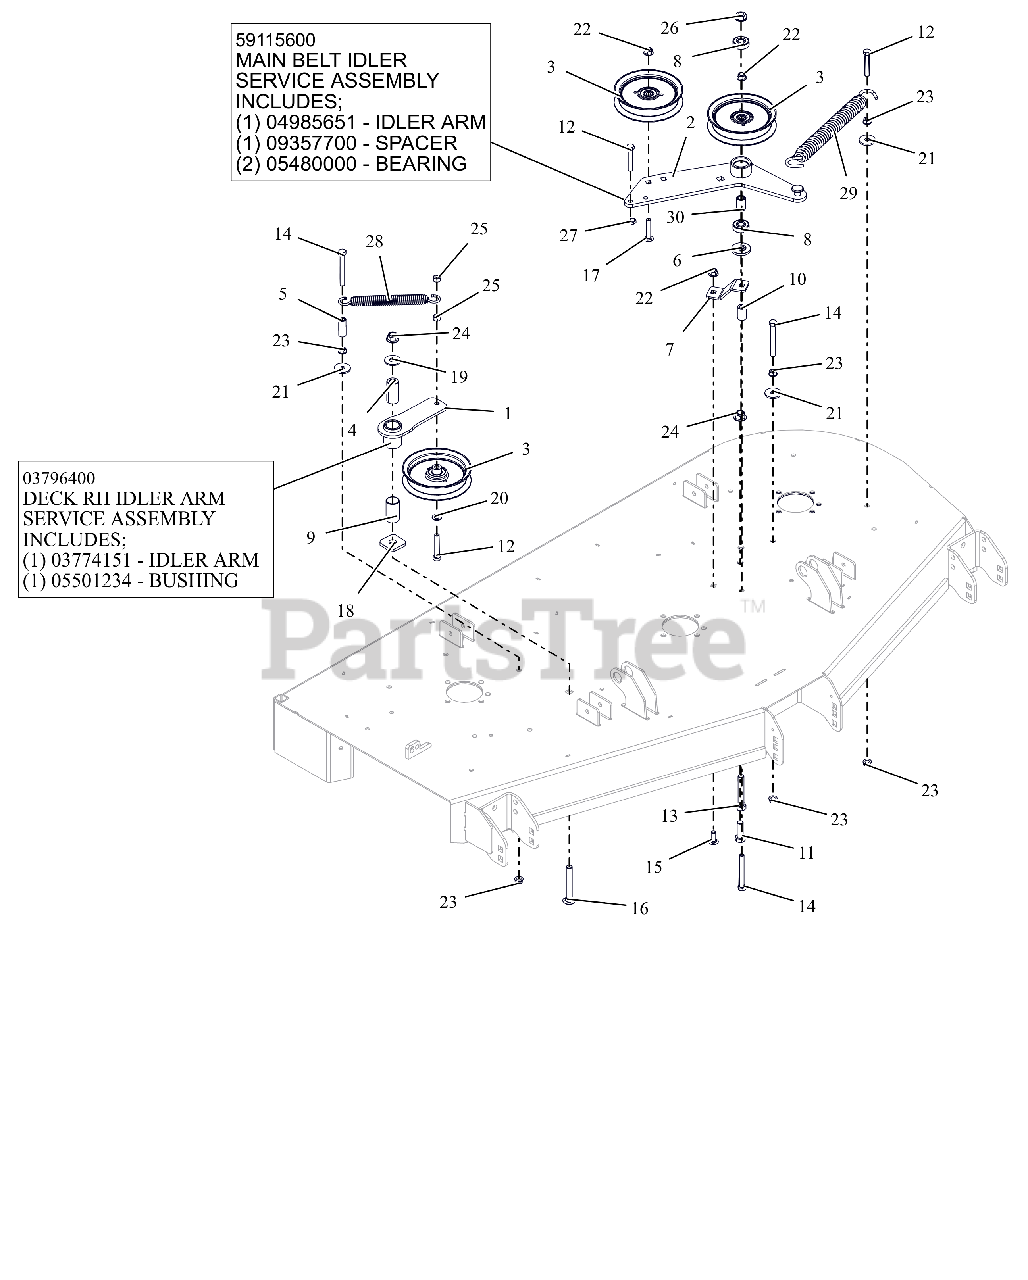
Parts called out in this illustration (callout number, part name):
1	WMT, IDLER ARM - BLACK
1	ASM, IDLER ARM (DECK)
2	DECK PTO IDLER ARM WLDMT - BLK
2	ASSEMBLY, MAIN BELT IDLER
3	IDLER, FLAT 5.00"
4	BSHG, SPCR .502X.997X2.03 PM
5	SPACER, .375IDX.625ODX1.66 PM
6	SPACER, IDLER ARM
7	PTO FIXED IDLER MTG BRKT -RED
8	BRG-BALL .500X1.38X.437
9	BSHG, 1.00X1.125X1.937
10	BUSHING, SLV .380X.750X1.190
11	BLT,HEX .50-13X1.50 G5 ZCC
12	BLT,HEX .38-16X2.25 G5 ZCC
13	BLT, HEX .50-13X3.00 G5 ZCC
14	BLT, HEX .38-16X3.25 G5 ZCC
15	BLT,RHSSN .38-16X1.00 G5 ZCC
16	BLT, RHSN .50-13X3.50 G5 ZCC
17	BLT,RHSSN.375-16X2.00 G5 ZCC
18	WSHR-FLT .640X1.75X.250
19	WSHR,FLT .563X1.375X.109 ZCC
20	WSHR,FLT .406X.812X.065 ZCC
21	WSHR,FLT .406X1.375X.135 ZCC
22	NUT,NYL-FLG .38-16 GF ZCC
23	NUT, SPNLK-FLG .38-16 G5 ZCC
24	NUT,NYL-FLG .50-13 GF ZCC
25	NUT-LK-CTR .38-16 ZC120
26	NUT-LK-CTR-FLG .500-13 GG ZCC
27	NUT-JAM .375-16 G2 ZCC
28	SPRING, EXTENSION
29	SPRING, EXTENSION
30	SPACER .510 X .75 X 1.1485
